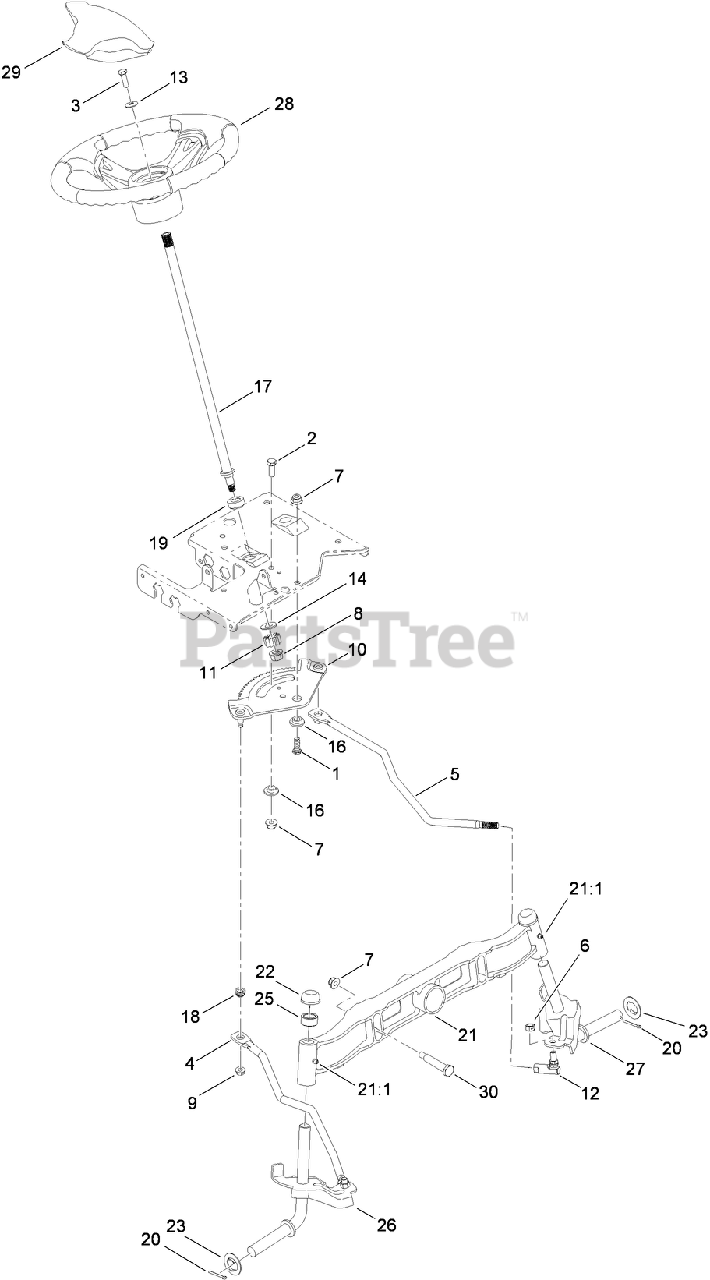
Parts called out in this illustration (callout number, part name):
1	SCREW-HH
2	SCREW-HH
3	SCREW-HH
4	LINK-DRAG, RH
5	LINK-DRAG, LH
6	NUT-HEX, LOCK
7	NUT-LOCK, FLANGE
8	NUT-LOCK, FLANGE
9	NUT-LOCK, FLANGE
11	GEAR-PINION, STEERING
12	BALL JOINT ASM
13	WASHER-FLAT
14	WASHER-FLAT
16	SPACER-SHOULDER
17	SHAFT-STEERING
18	BUSHING
19	BEARING-FLANGE, HEX
20	PIN-COTTER
21	PIVOT-AXLE, CAST IRON
21:1	FITTING-GREASE
23	WASHER-FLAT
25	SPACER
26	RH AXLE ASM
27	LH AXLE ASM
28	WHEEL-STEERING, SOFTGRIP
29	COVER-WHEEL, STEERING
30	BOLT-SHOULDER
